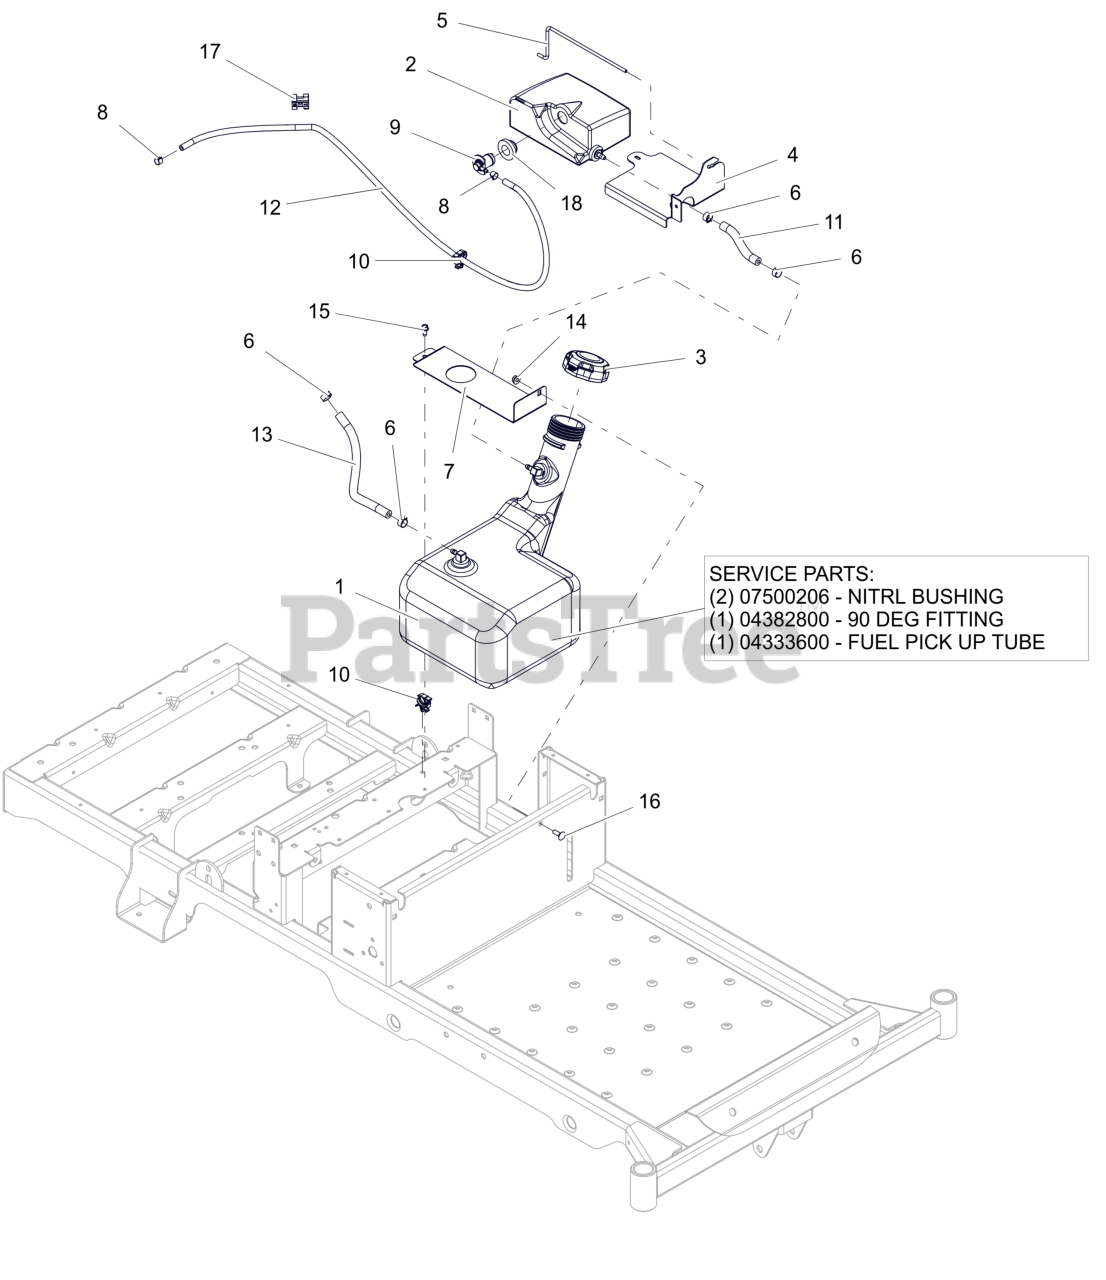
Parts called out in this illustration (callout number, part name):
1	ASM, FUEL TANK-ZOOM
1	BSHG-FLG .375X1.062X.625 NITR
1	FITTING, 90 DEG FUEL-PLASTIC
1	FUEL PICK UP TUBE
2	ASM, FUEL TANK - EXPANSION
3	CAP, FUEL - 2.25 RATCHET INLET VENT
4	BRKT, EXPANSION TANK (ORANGE)
5	ROD, HOLDDOWN (BLACK)
6	CLAMP, FUEL LINE
7	BRKT, TANK STRAP
8	CLAMP-HOSE, SPRING .188
9	VALVE, 2-WAY
10	WIRE CLIP
11	HOSE, .25 LOW-PERM BULK GAS
12	HOSE, .188 LOW-PERM BULK GAS
13	HOSE, .25 LOW-PERM BULK GAS
14	NUT-LK-CTR-FLG .25-20 ZC120
15	SCR-TAP .25-20X.50 HWH ZCC
16	BLT, RHSN .25-20X.750 G5 ZCC
17	CLIP, T, .38-.50
18	GROMMET, REMOTE VENT NITRILE
